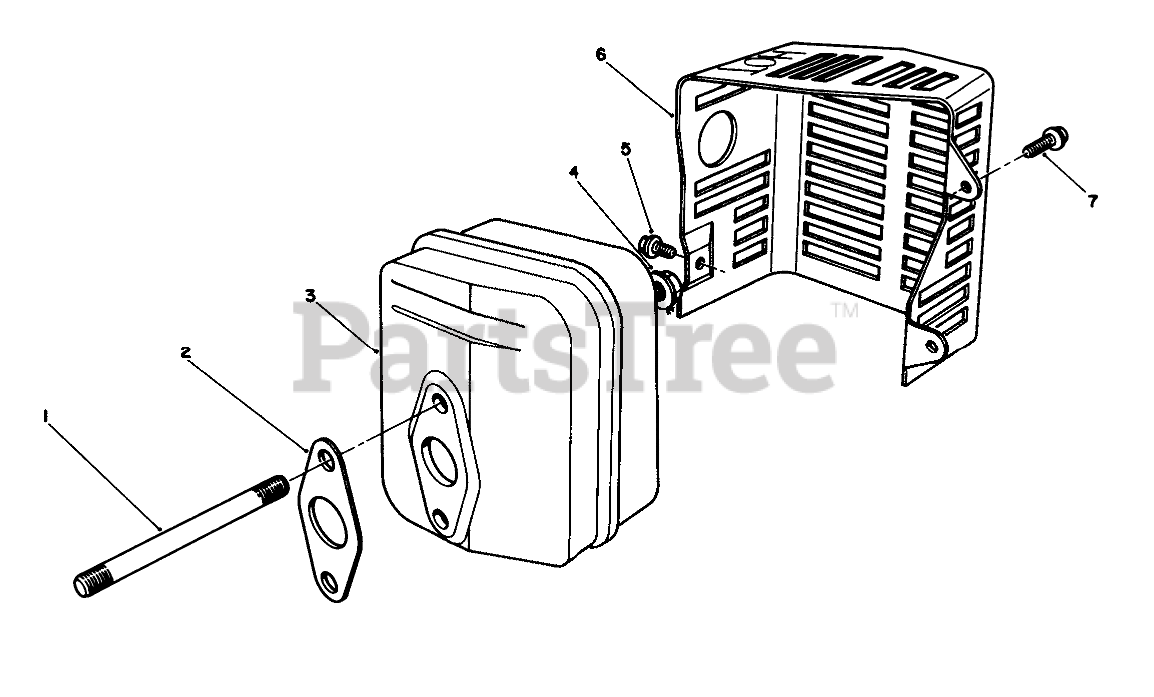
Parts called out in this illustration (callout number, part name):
2	GASKET
3	MUFFLER
4	GROUND TERMINAL
5	SCREW
6	COVER
